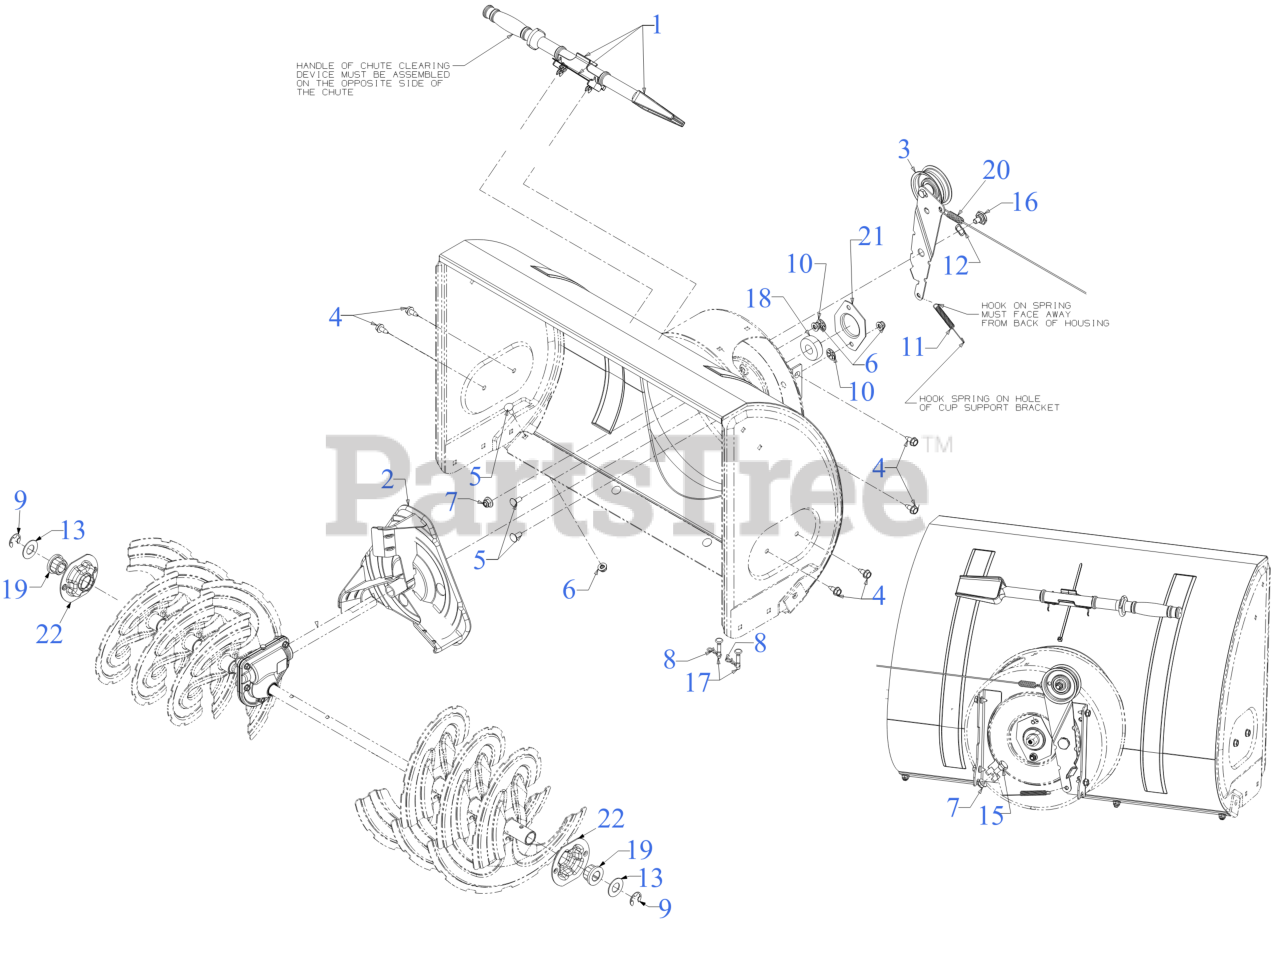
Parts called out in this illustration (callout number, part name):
1	CLEANOUT TOOL
1	CLEANOUT TOOL MOUNTING CLIP
1	7" CABLE TIE
3	FLAT IDLER PULLEY 2.75 OD
3	AUGER IDLER BRACKET
3	HEX SCREW 3/8-16 x 1.75 GR5
4	SCREW 5/16-18 x .750
5	CARRIAGE BOLT 5/16-18 x .75
6	FLANGE LOCK NUT 5/16-18
8	BOW TIE COTTER PIN 1/4-5/16
10	PUSH ON NUT
11	EXTENSION SPRING .38 OD x 4.59
12	WAVE WASHER .660 ID X.88 OD x .010
13	FLAT WASHER
15	SHOULDER SCREW .498 DIA x .340
16	SHOULDER SCREW .625
17	SHEAR PIN .25 x 1.50 GR2
18	BEARING W/OUT COLLAR
19	FLANGE BEARING
20	AUGER DRIVE CABLE 47.48"
21	BEARING HOUSING 1.85 ID
